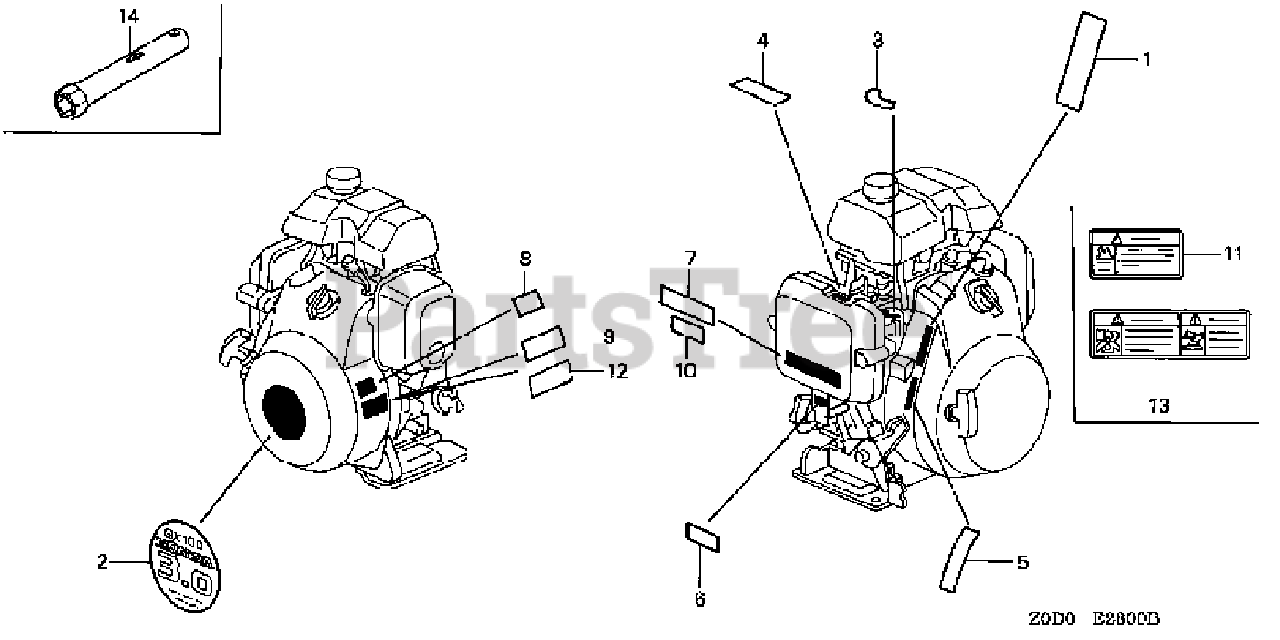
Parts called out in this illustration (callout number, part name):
2	EMBLEM (RAMMER)
4	MARK, CHOKE INDICATION
6	MARK, TYPE (KRB)
14	WRENCH, SPARK PLUG
